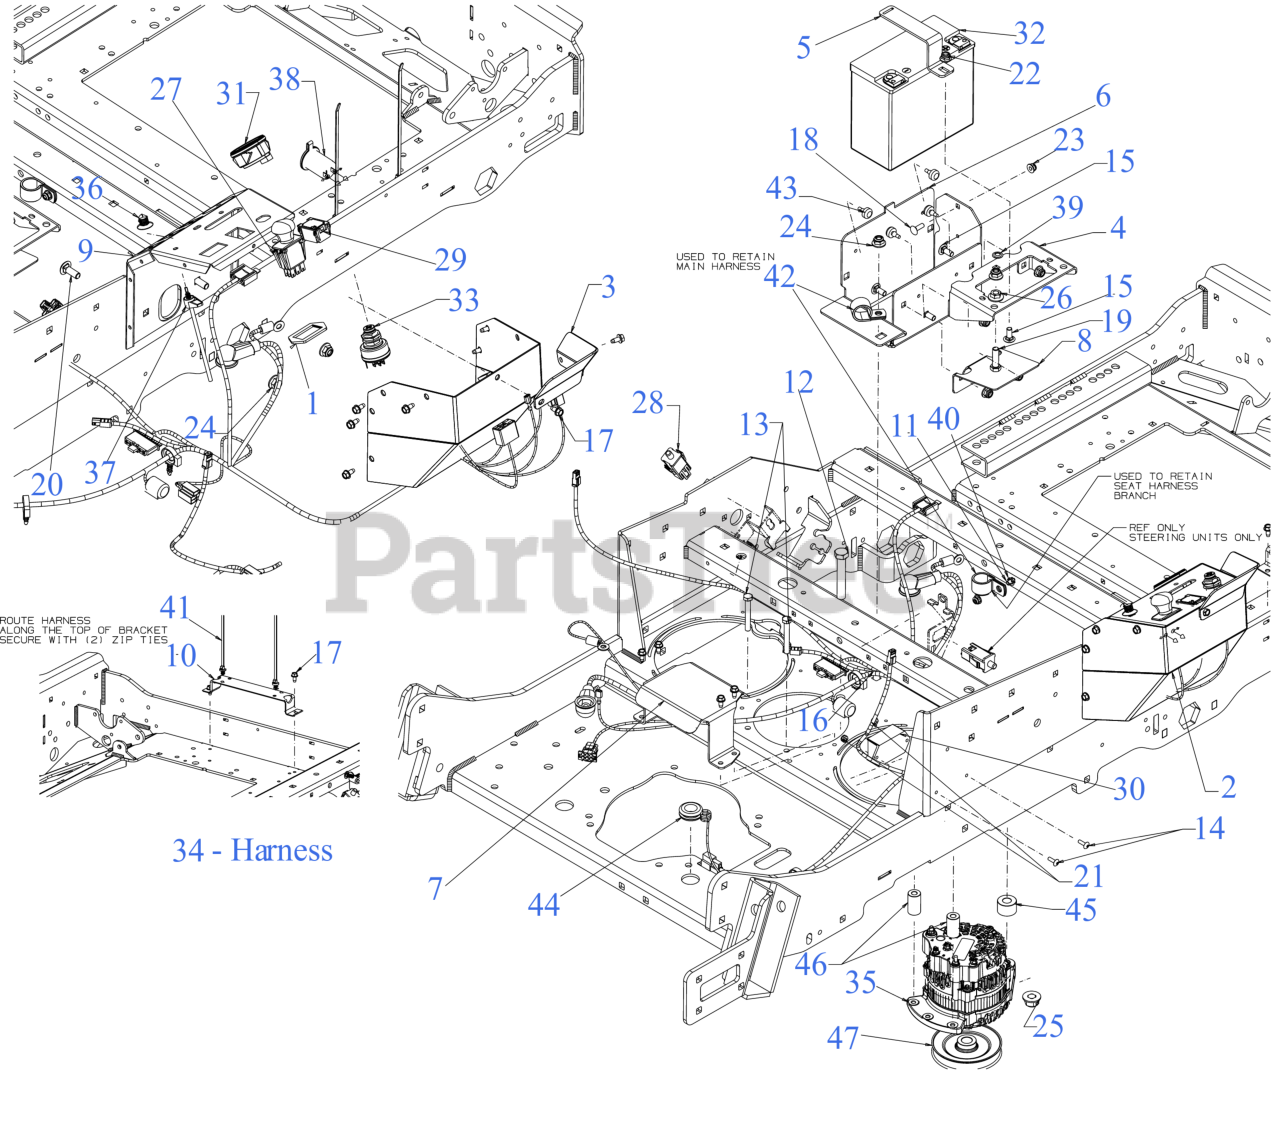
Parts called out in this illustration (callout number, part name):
1	BRACKET-PTO SWITCH
4	FUSE/RELAY MOUNT BRACKET
5	BATTERY SUPPORT BRACKET
6	BATTERY MOUNT BRACKET
7	ALTERNATOR COVER BRACKET
8	HARNESS GUARD PLATE
9	CONTROL POD (RH)
10	HARNESS GUIDE BRACKET
11	CARRIAGE BOLT 1/4-20 x .62
12	SCREW-HEX 1/2-13 x 3.00
13	HEX SCREW 5/16-18 x 2.25 GR5
14	SCREW #10-24 x .62
15	CARRIAGE BOLT 5/16-18 x .75
16	CARRIAGE BOLT 3/8-16 X1.25 GR5
17	SCREW 1/4-20 X.500
18	SCREW 1/4-20 x .75 GR5
19	SCREW 3/8-16 x 1.25 GR5
20	CARRIAGE BOLT 3/8-16 x 1.00 GR5
22	FLANGE LOCK NUT 5/16-18
23	FLANGE LOCK NUT
26	FLANGE LOCK NUT
27	PTO SWITCH (BLACK KNOB) TEXT SYM
28	3 POLE SWITCH ( NC-NO-NO)
30	CONTROL PANEL (SOFT CLUTCH)
31	DUAL FUEL GAUGE
32	BATTERY (300 CCA)
33	KEY SWITCH
35	ALTERNATOR 70A
37	ROTARY SWITCH
38	POWER RECEPTICAL
40	RETAINER-BOLT .25ID x .50OD
41	CABLE TIE
42	HOSE CLAMP 1.0"
43	BUMPER, .62 DIA x .3
44	RUBBER GROMMET
45	SPACER (LARGE)
46	SPACER (SMALL)
47	ALTERNATOR PULLEY
